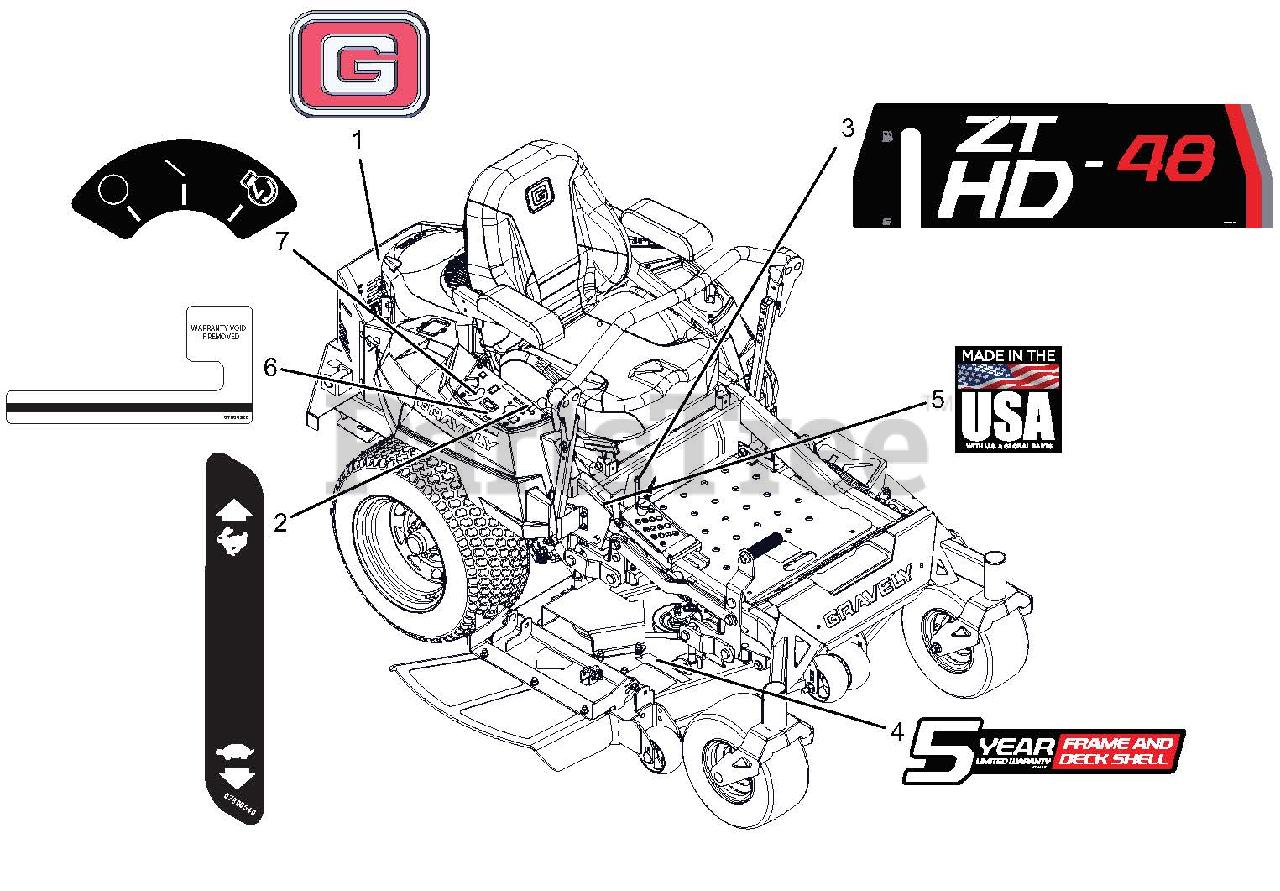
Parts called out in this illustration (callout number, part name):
1	DECAL, GRAVELY BRAND
2	DECAL, DASH DECAL
3	DECAL - 48HD
4	DECAL, DECK 5 YEAR-GRAVELY
5	DECAL, MADE IN USA
6	DECAL,HOURMETER - SECURITY
7	DECAL, KEYSWITCH
